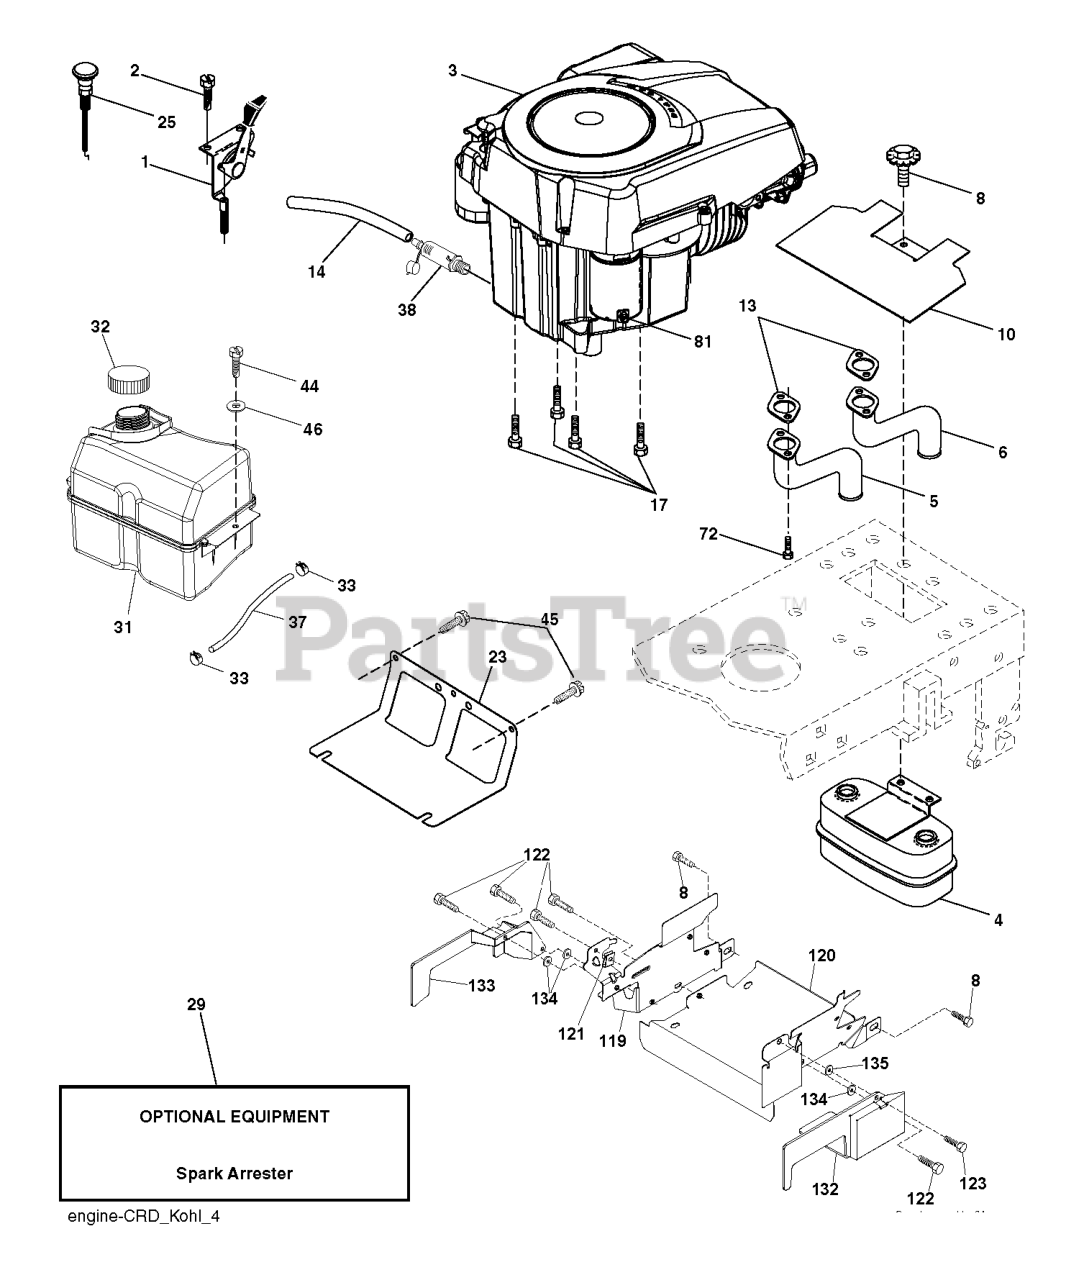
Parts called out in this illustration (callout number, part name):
1	THROTTLE CONTROL
2	SCREW.#10 X 0.750.BOS
4	MUFFLER.TWIN.CYL.LOW.TONE
5	RP.PIPE-EXHAUST LH
6	RP.PIPE-EXHAUST RH
8	BOLT.5/16-18UNCX3/4 W/SEMS.BLK
10	RP SHIELD HEAT MUFFLER
13	GASKET.EXHAUST.KOHL.CV18-CV26
14	TUBE, DRAIN OIL ASM.
17	SCREW 3/8-16X1
23	SHIELD.BROWNING.DBR.GUARD
25	CONTROL, CHOKE
29	KIT.SPARK ARRESTOR 794945 B&S
31	TANK.ASM.FUEL.FR.2.5GA.
32	FUEL CAP
33	HOSE CLAMP
37	LINE.FUEL.20
38	PLUG DRAIN OIL EASY
44	SCREW HEXWSHR 1/4-20X3/4
45	SCREW, 3/8-16X3/4
72	SCREW.SOCKET HD.5/16-1
81	NUT
119	LENKRAD
120	GUARD 532199767
122	SCREW.1/4-20X5/8
123	SCREW, 5/16-18 X 1/2
132	SHIELD RIGHT
133	SHIELD LEFT
134	PALNUT 1/4
135	WASHER 5/16"
